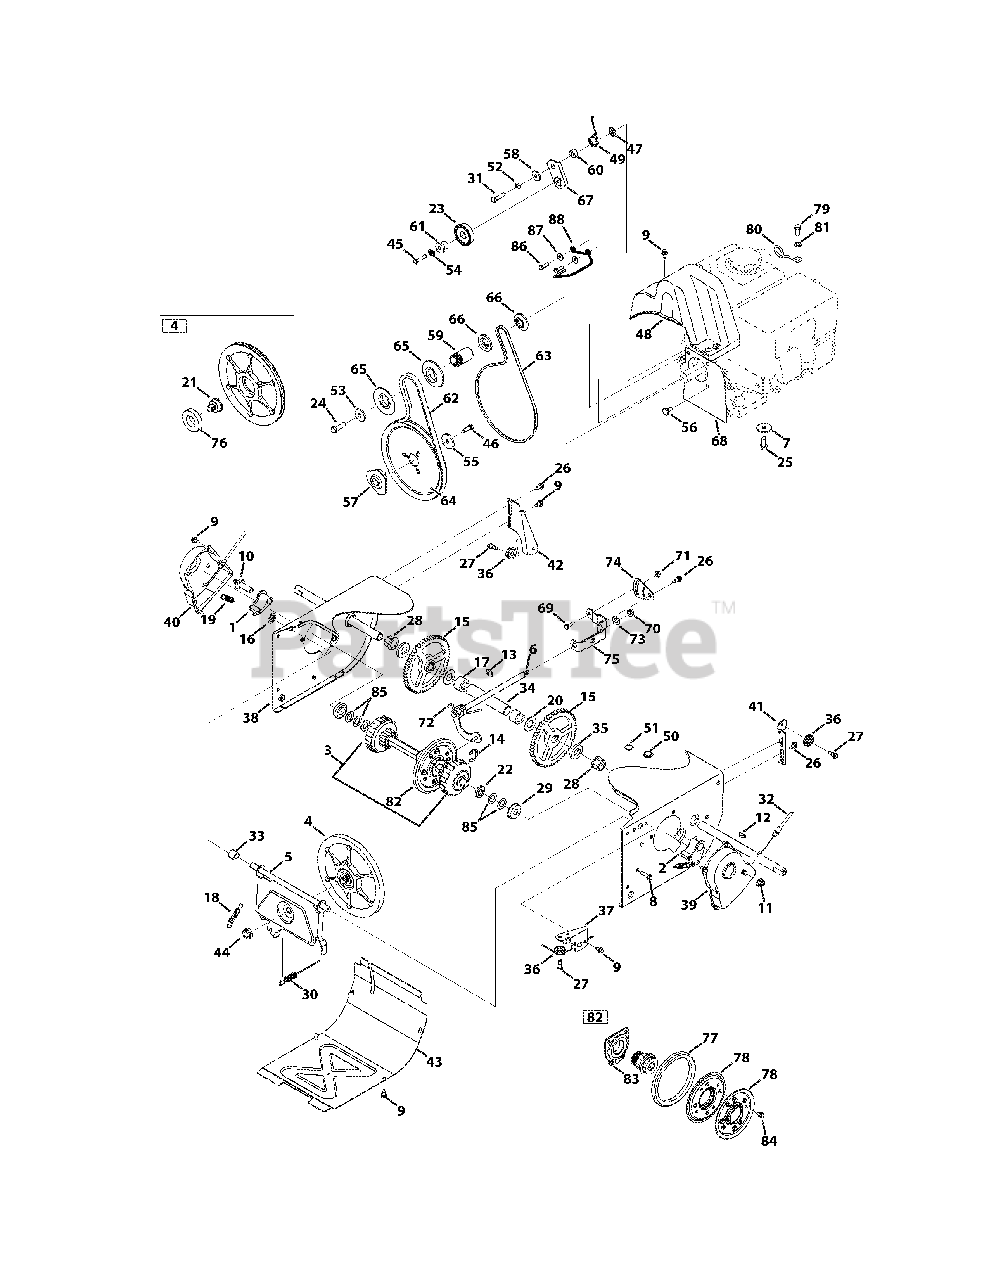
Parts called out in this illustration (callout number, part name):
1	Dogg Assembly, RH
2	Dogg Assembly, LH
3	Drive Shaft Assembly
4	Friction Wheel Disc Assembly
5	Friction Wheel Support
6	Rod Shift Assembly
7	Washer, Flat, .38 x 1.38
8	Screw, 1/4-20 x 1.000
9	Screw, 1/4-20 x .625
10	Actuator Shaft
11	Nut, Flangelock, 3/8-16
12	Hi-Pro Key, 3/16 x 3/4 DIA
14	Retainer Ring
16	Nut, Speed, .500
17	Spacer, .76 x .75
18	Extension Spring, .380 x 2.500
19	Extension Spring, .500 x 1.71
20	Washer, Flat, .76 x 1.49
21	Friction Pin, Disc Bearing
22	Spacer, .68 ID x 1.25 OD x .20
23	Pulley Assembly
24	Hex Head Screw, 3/8-24 x 1.25
25	Taptite Sems Screw, 3/8-16 x 1.000
26	Screw, Shoulder, .368 x .113 x 1/4-20
27	C Screw, Shoulder, .340 x .335 x 1/4-28
28	Hex Flange Bearing, .75 ID
29	Ball Bearing, 17 x 40 x 12
30	Drive Clutch Cable
31	Hex Head Screw, 5/16-24 x 1.25
32	Steering Cable
33	Spacer, .508 x .75
34	Axle Support Tube
35	Spacer, Axle
36	Roller Cable
37	Auger Cable Guide Bracket
38	Wheel Drive Frame
39	Shaft Retainer, LH
40	Shaft Retainer, RH
41	Auger Clutch Cable Guide Bracket
42	Drive Clutch Cable Guide Bracket
44	Nut, Flange, 5/8-18
45	Taptite Screw, 1/4-20 x 1.250
46	Hex Head Screw, 5/16-24 x .875
47	Nut, Push-On, .25 DIA
48	Belt Cover, 4-Way lrg. block
49	Spring, Torsion, .850 x .333
50	Plug, 3/8 ID
51	Plug, 1/2 ID
52	Washer, Lock, 5/16
53	Washer, Flat, .45 x 1.5
54	Washer, Lock, 1/4
55	Washer, Flat, .34 x 1.50
56	Screw, Shoulder
57	Pulley Adapter, .75 DIA
58	Spacer, Shoulder, .3175 x .500
59	Spacer, .875 x 1.185
60	Spacer, .340 x .750
61	Spacer, Shoulder, .260 x .785
62	Auger Drive Belt, 4-Way lrg. block
63	V Belt, 3L x 36.64"
64	Auger Pulley, 8.1 x .5
65	Pulley, Half, 4L-V x 2.600
66	Pulley, Half, 3/8-V x 2.2
67	Drive Idler Bracket
68	Cover Plate, 4-Way lrg. block
69	Hex Head Screw, 1/4-20 x .620
70	Nut, Flangelock, 5/16-18
71	Nut, Flangelock, 1/4-20
72	Spring, Torsion, .750 x .968
73	Washer, Flat, .469 x .875 x .105
74	Speed Selector Pivot Bracket
75	Speed Selector Shift Bracket
76	Ball Bearing, 30 x 55 x 13
77	Friction Wheel, 5.5 OD
78	Friction Wheel Plate
79	Hex Head Screw, 1.25 x 20
80	Cable Guide
81	Washer, Flat, .330 x .630
82	Friction Wheel Assembly
83	Bearing Assembly, Friction Wheel
84	Screw, 5/16-18 x .750
85	Flat Washer, .67 x 1.174 x .02
86	Hex Head Screw, 5/16-24 x 1.00
87	Washer, Flat, .349 x .879
